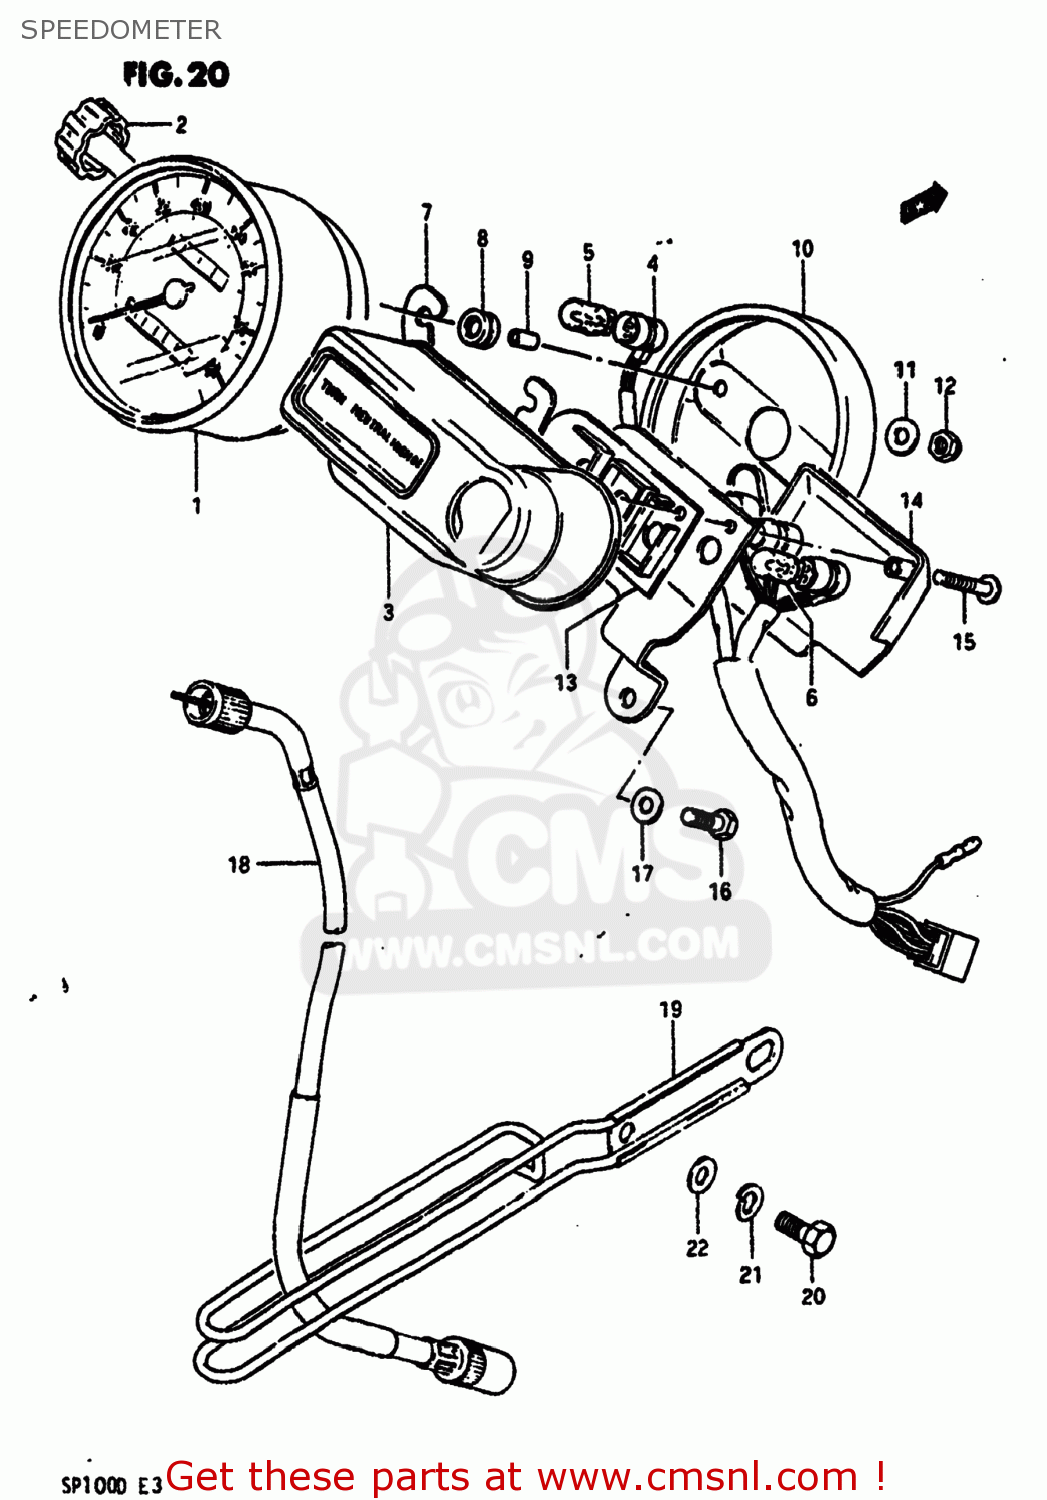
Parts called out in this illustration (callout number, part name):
1	SPEEDOMETER ASSEMBLY
2	KNOB,TRIP
3	CASE,PILOT BULB
4	SOCKET,METER
5	BULB(6V,3W)
6	BULB(6V1.7W,STANLEY,A61A)
7	BRACKET,METER
8	CUSHION,METER
9	SPACER,METER
10	BRACKET,SPEEDOMETER,UNDER
11	WASHER,METER
12	NUT
13	HOLDER,SOCKET
14	COVER,PILOT BOX
15	SCREW
16	BOLT
17	WASHER
18	CABLE ASSEMBLY,SPEEDOMETER
19	GUIDE,CABLE
20	BOLT 8X12
21	LOCK WASHER
22	WASHER
